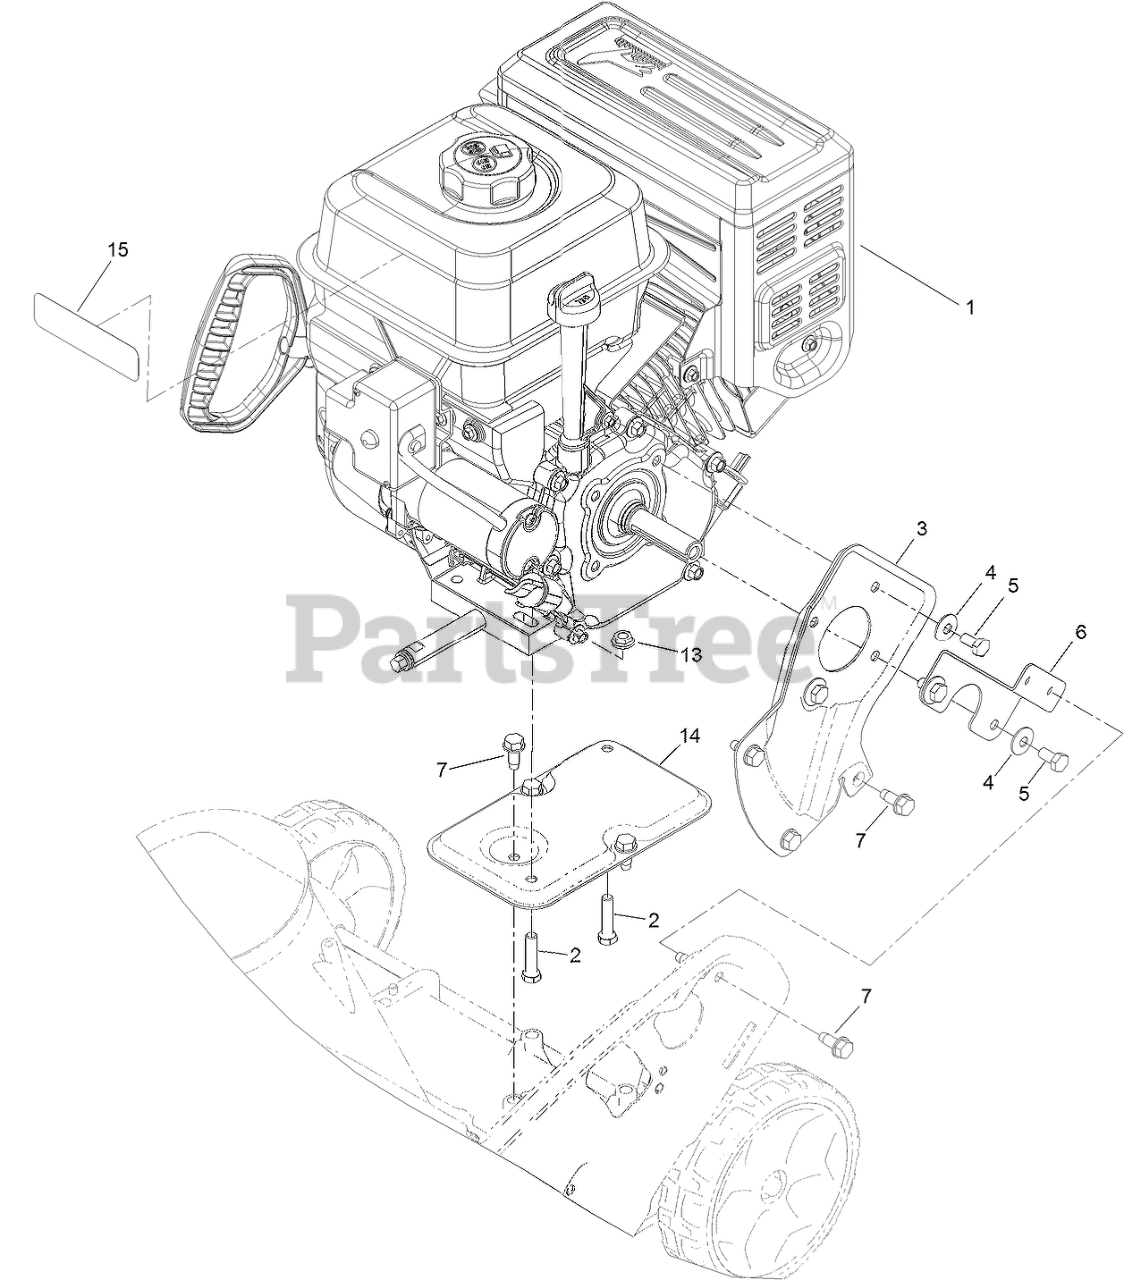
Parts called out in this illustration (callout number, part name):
1	ENGINE - G250FS-4
2	SCREW-HH
3	PLATE-ENGINE, PTO
4	WASHER-BELLEVILLE
5	BOLT
6	SUPPORT-ENGINE, SIDE
7	SCREW-THD ROLL, HWH
13	NUT-HF
14	SUPPORT-ENGINE
15	DECAL-ENGINE COMMERCIAL
